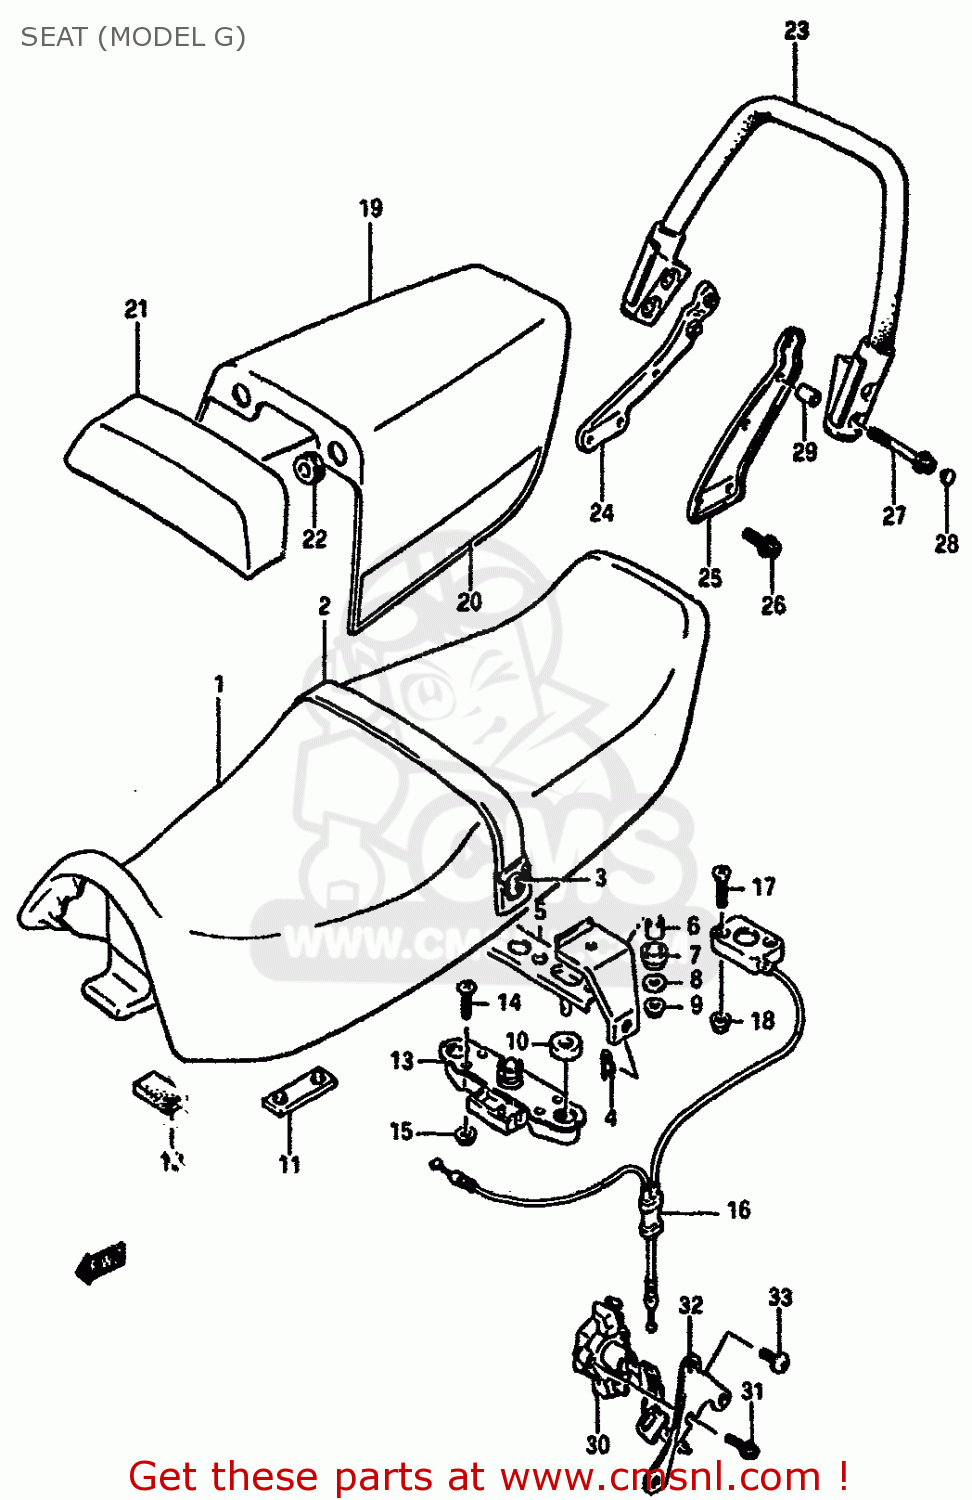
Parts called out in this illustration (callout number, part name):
1	SEAT ASSEMBLY
2	BAND,SEAT GRIP (RED)
3	BOLT
4	CLIP
5	STRIKER,SEAT LOCK
6	CUSHION
7	SPACER
8	WASHER
9	NUT
10	CUSHION
11	CUSHION
12	CUSHION
13	LOCK ASSY,SEAT STRIKER
14	SCREW
15	NUT
16	BRACKET,SEAT SUPPORT RR
17	SCREW
18	NUT
19	BOX,SEAT TAIL
20	TAPE SET,SEAT TAIL BOX
21	BACKREST,SEAT
22	CUSHION
23	HANDLE,PILLION RIDER
24	PLATE,PILLION HANDLE,R
25	PLATE COMP,PILLION HANDLE
26	BOLT
27	BOLT
28	CAP(OD:10)
29	SPACER (8.6X13.8X21.5)
30	LOCK SET
31	PLUG ,6X20
32	BRACKET,SEAT LOCK
33	SCREW 6X12
